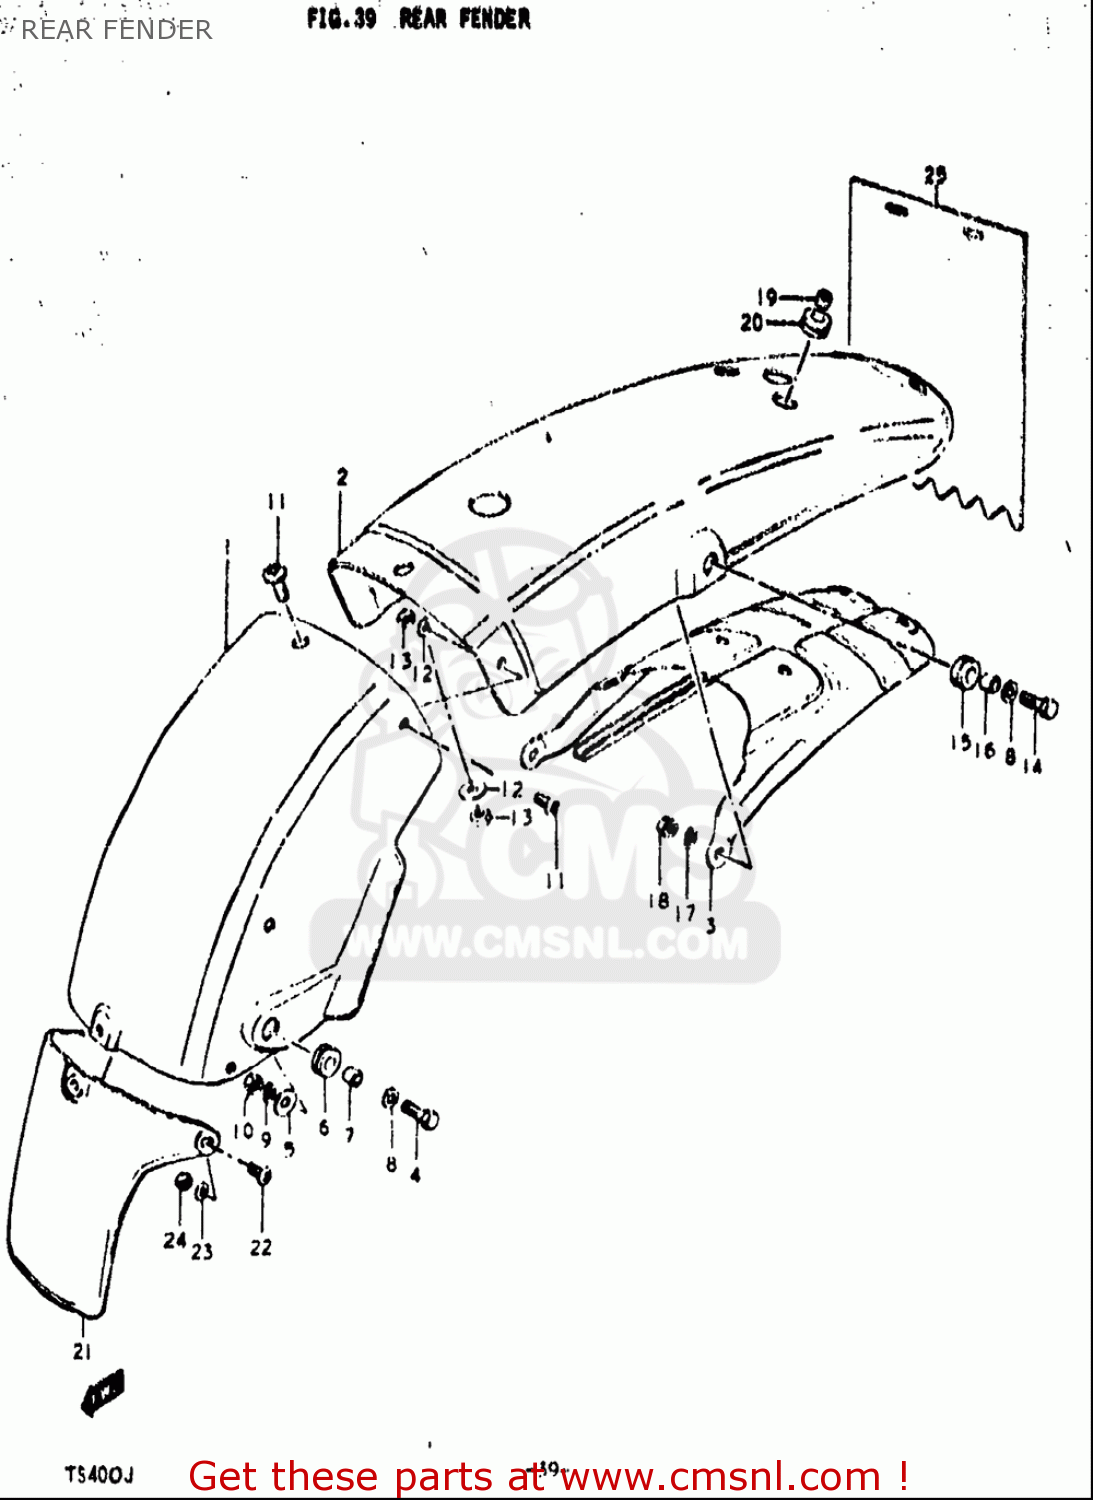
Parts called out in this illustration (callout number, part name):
4	BOLT
5	WASHER(6.5X20X1.2)
6	CUSHION
7	SPACER(6.1X9X7.5)
8	WASHER
9	WASHER,LOCK
10	NUT
11	SCREW
12	WASHER
13	NUT
14	BOLT
15	CUSHION
16	SPACER(6.1X9X7.5)
17	WASHER,LOCK
18	NUT
19	SPACER(6.1X9X7.5)
20	CUSHION
22	SCREW
23	WASHER
24	NUT
